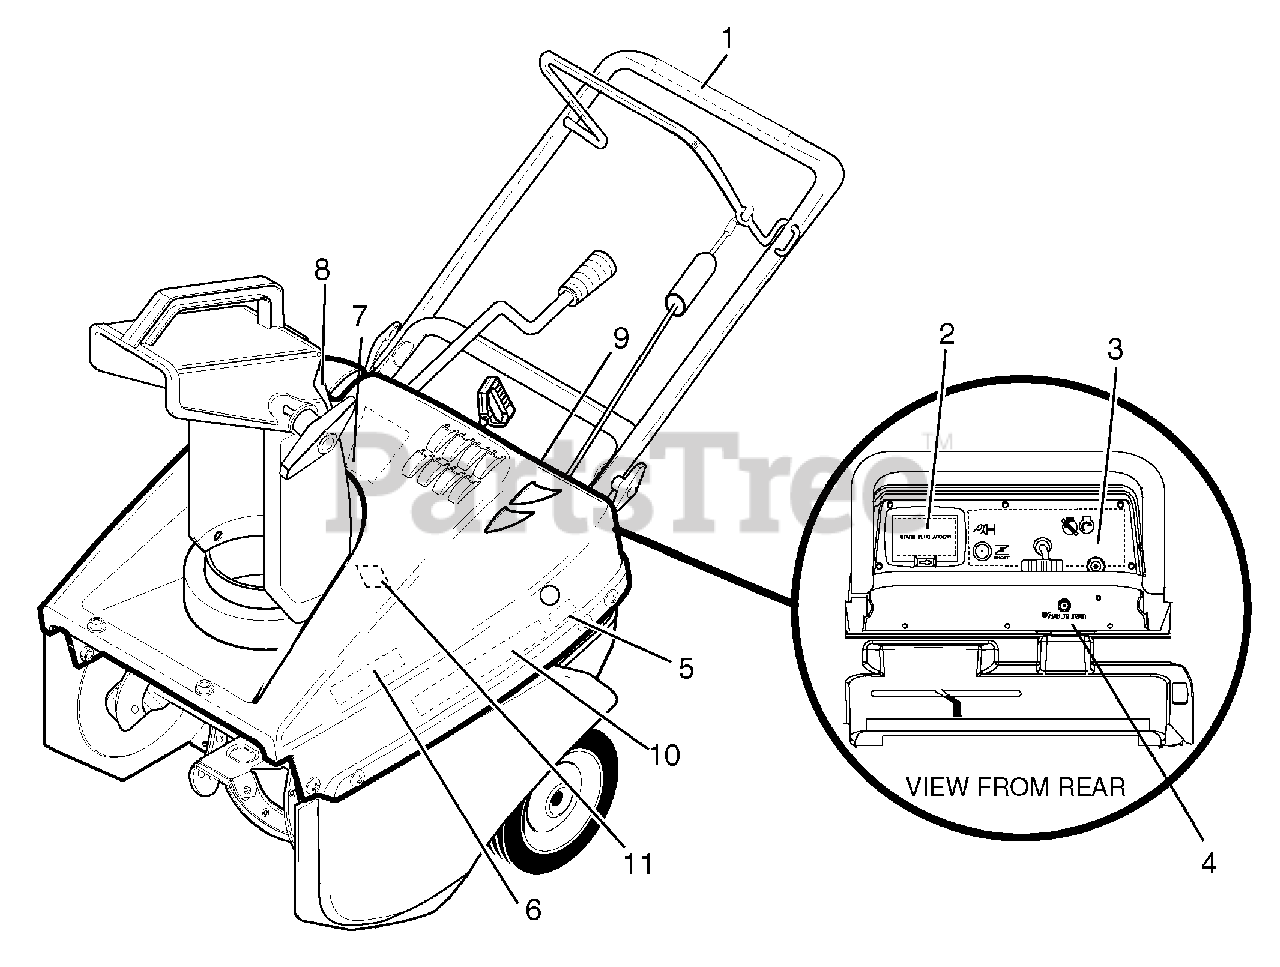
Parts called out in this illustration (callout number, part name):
1	DECAL, Auger Control Bar
2	DECAL, Spark Plug Access
3	DECAL, Dash, 21" French/English
4	DECAL, Push To Start
5	DECAL, Danger, Muffler
6	DECAL, Auger French/English
7	DECAL, 521E
8	DECAL, Danger Auger Chute French/English
9	DECAL, Access Cover Warning
10	DECAL, Logo, Snapper
11	DECAL, Briggs & Stratton Logo
